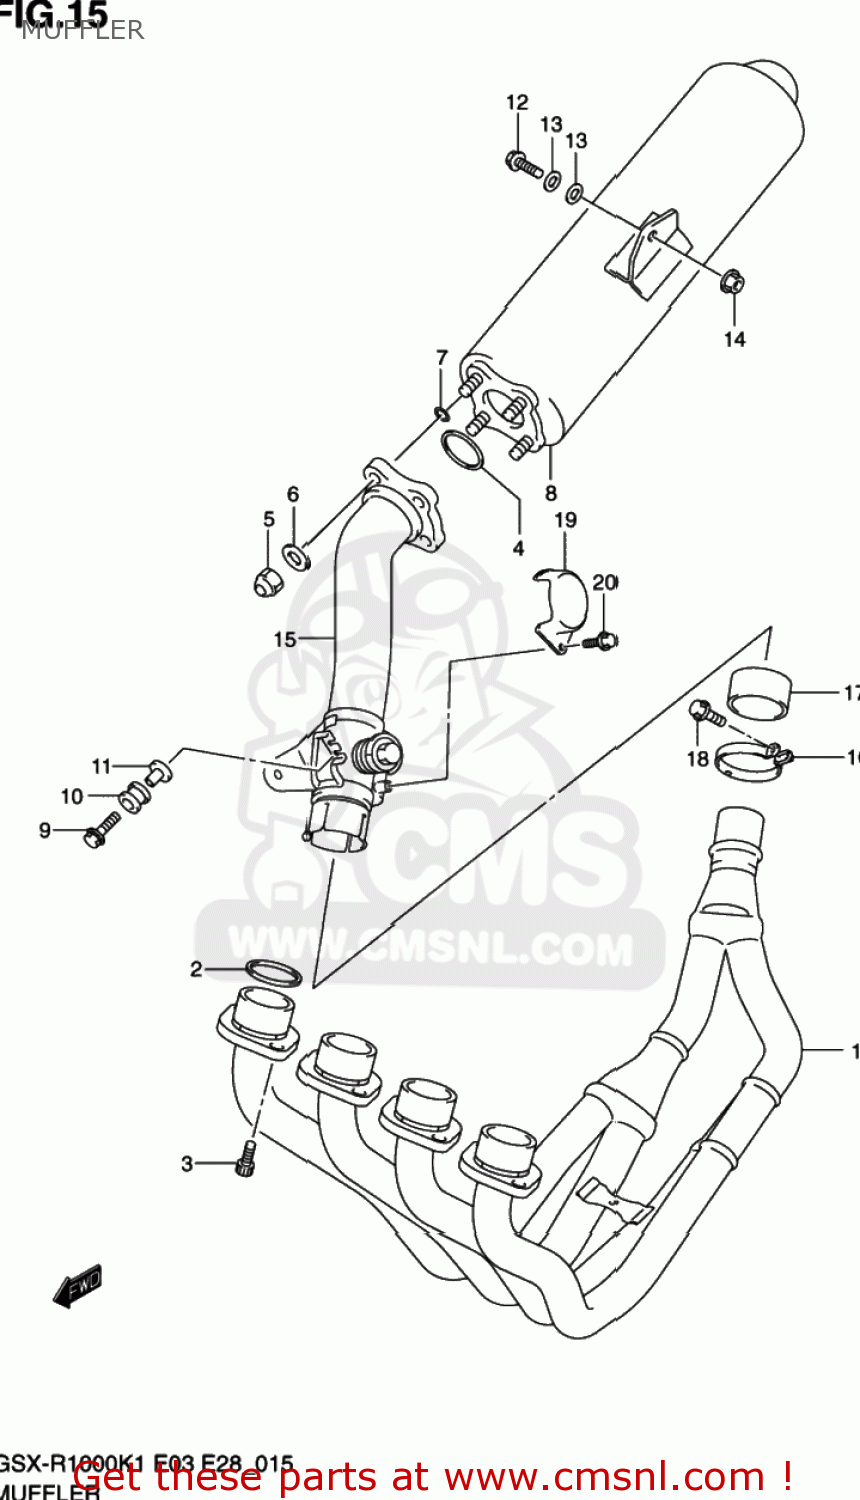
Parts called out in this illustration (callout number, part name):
1	EXHAUST
2	GASKET,EXHAUST PIPE
3	BOLT
4	GASKET,MUFFLER JOINT (NAS)
5	NUT
6	WASHER(8.5X18X1.6)
7	O RING(D:1.9,ID:7.8)
8	BODY,MUFFLER
9	BOLT 8X45
10	CUSHION
11	SPACER(8.6X12X24.2)
12	BOLT(8X35)
13	WASHER(8.5X23X1.5)
14	NUT
15	JOINT
16	CLAMP,CONNECTOR
17	CONNECTOR,JOINT
18	BOLT
19	COVER,EXHAUST VALVE
20	BOLT(6X8)
